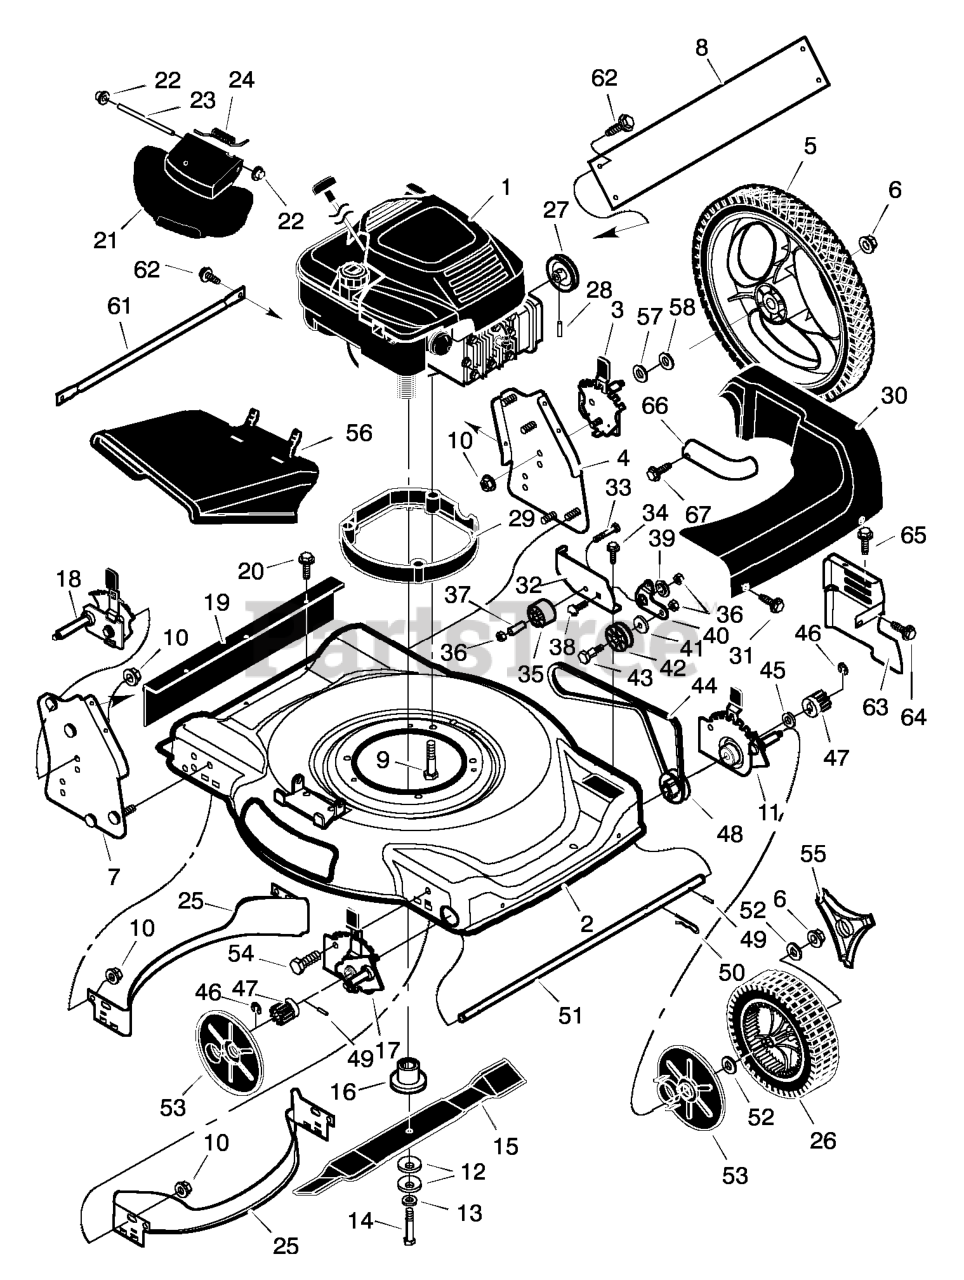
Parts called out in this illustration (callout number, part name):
1	Engine *
2	Housing
3	Height Adjuster, Left Rear
4	Bracket, Left Handle
5	Wheel and Tire, Rear
6	Locknut, Flange
7	Bracket, Right Handle
8	Brace, Handle Bracket
9	Bolt, Engine
10	Nut
11	Height Adjuster, Left Front
12	Washer, Belleville
14	Bolt, Hex
16	Adapter, Blade
17	Height Adjuster, Right Front
18	Height Adjuster, Right Rear
19	Guard, Rear
21	Cover, Mulcher
22	Push- On Cap
23	Pin, Pivot
26	Wheel and Tire, Drive
28	Pin, Spring
29	Base, Engine
30	Cover, Belt
32	Bracket, Idler Support
36	Locknut
37	Bearing
38	Bolt, Carriage
40	Arm, Idler
42	Pulley, Idler
43	Bolt, Shoulder
46	Ring, Retainer
47	Gear, Pinion
49	Pin, Drive
50	Pin, Hair
52	Washer
53	Cover, Dust
54	Bolt
55	Hub Cap
56	Deflector, Chute
63	Shield, Heat
64	Screw
66	Tube, Exhaust
